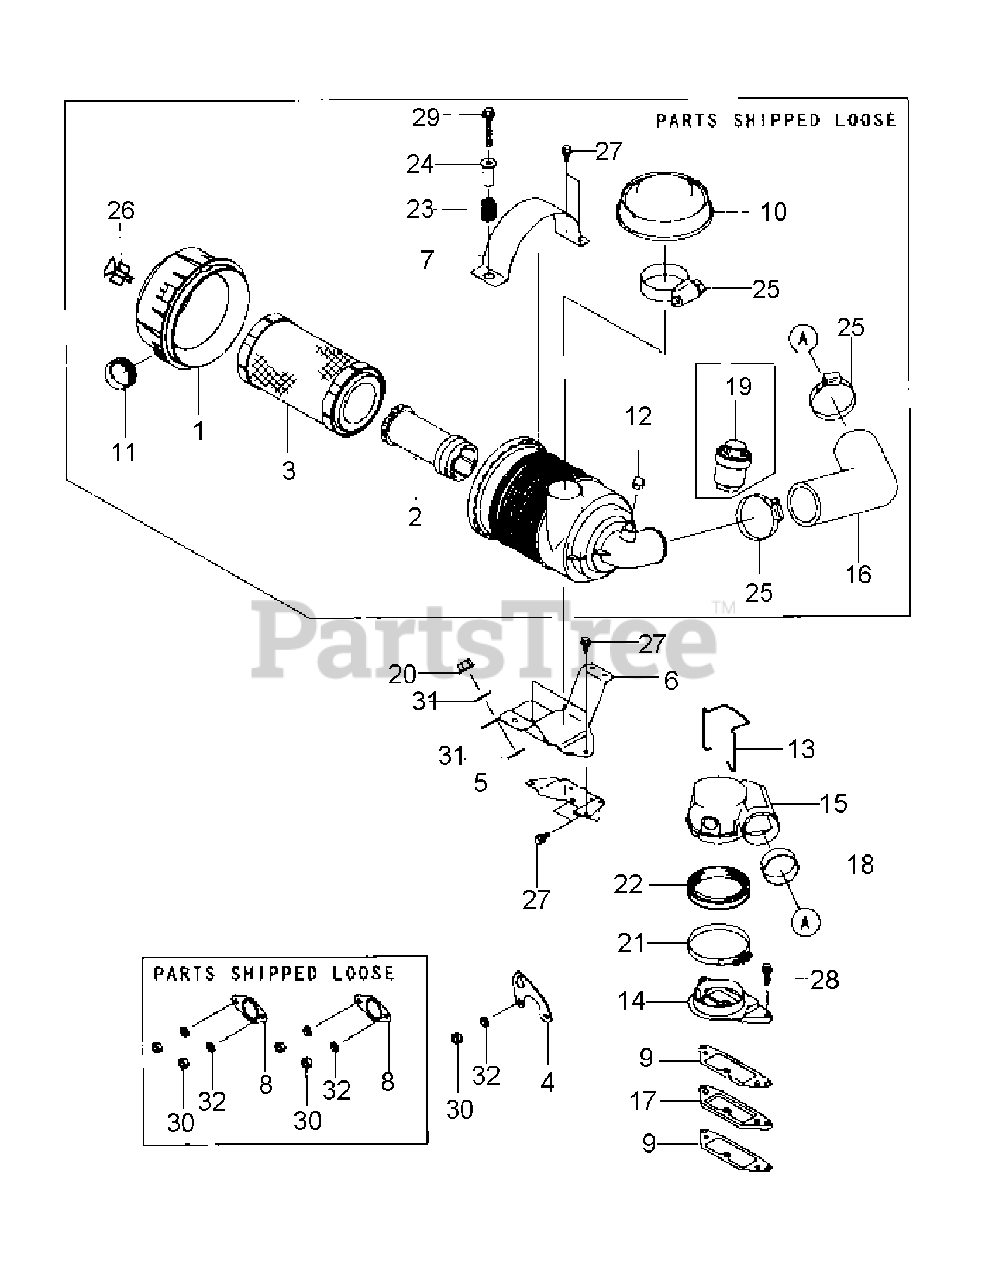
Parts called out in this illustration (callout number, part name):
1	AIR FILTER CASE
2	AIR FILTER (INNER) SECONDARY
3	AIR FILTER (OUTER) PRIMARY
8	MUFFLER GASKET
10	CAP
14	LOWER DUCT
16	INTAKE PIPE
25	CLAMP
27	FLANGED BOLT
28	FLANGED BOLT
29	FLANGED BOLT
30	HEX NUT SMALL
31	PLAIN WASHER
32	SPRING WASHER
